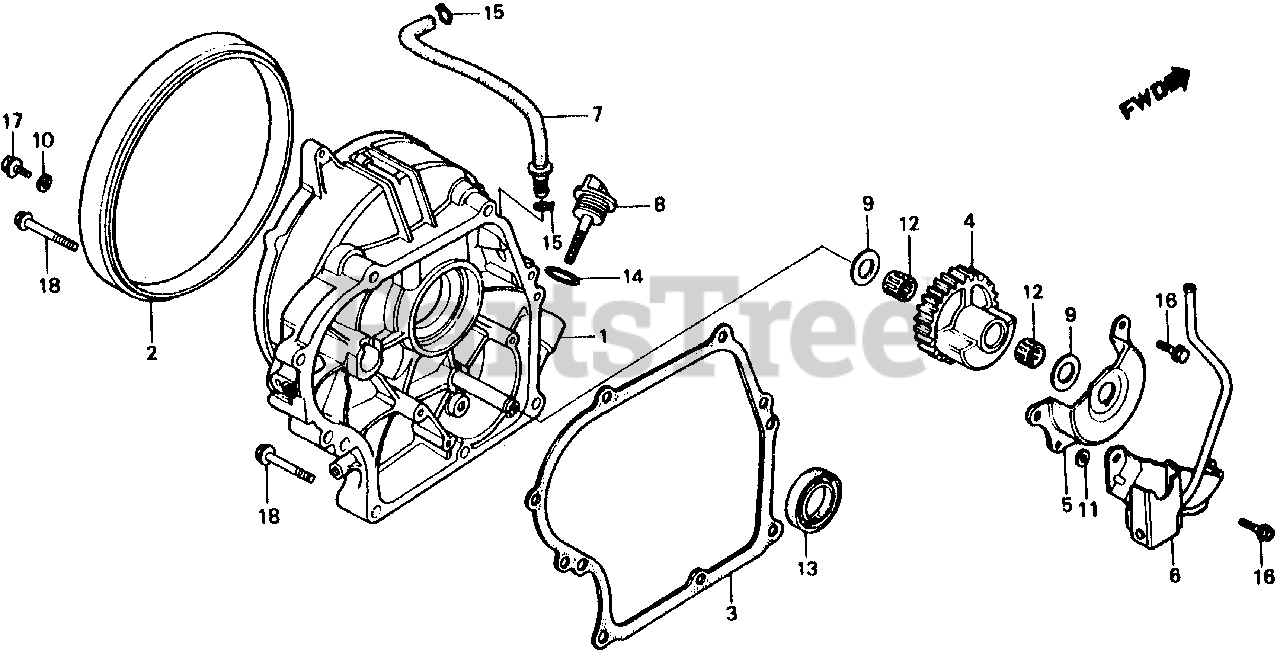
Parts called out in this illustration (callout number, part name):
1	COVER, CRANKCASE (NOT AVAILABLE)
2	RING, SPACER
3	GASKET, CASE COVER
4	WEIGHT, BALANCER
5	COVER, BALANCER
7	TUBE, OIL ALERT
8	CAP, OIL FILLER
9	WASHER, THRUST (15MM)
10	WASHER A (8MM)
11	WASHER, CRANK ARM
12	BEARING, NEEDLE
13	OIL SEAL (30X46X8)
14	O-RING (26X2.7)
15	CLIP, TUBE (C11)
16	BOLT, FLANGE (6X16)
17	BOLT, FLANGE (8X12)
18	BOLT, FLANGE (8X45)
